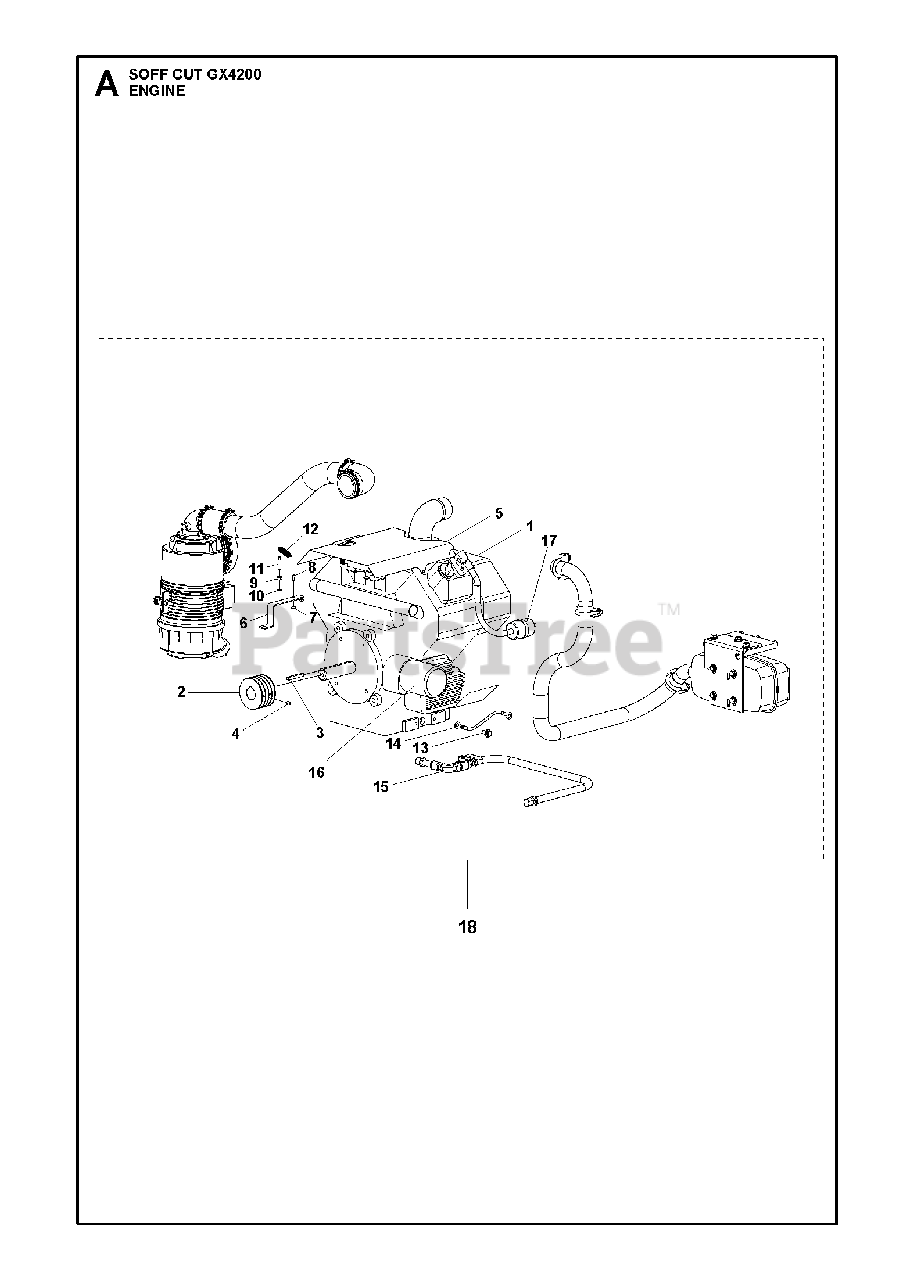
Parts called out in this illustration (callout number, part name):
2	PULLEY"Rail 14"", Incl. 2 - 4 "
3	KEY"Rail 16"", Incl. 2 - 4 "
10	WASHER"14"", 16"", Rail 14"""
